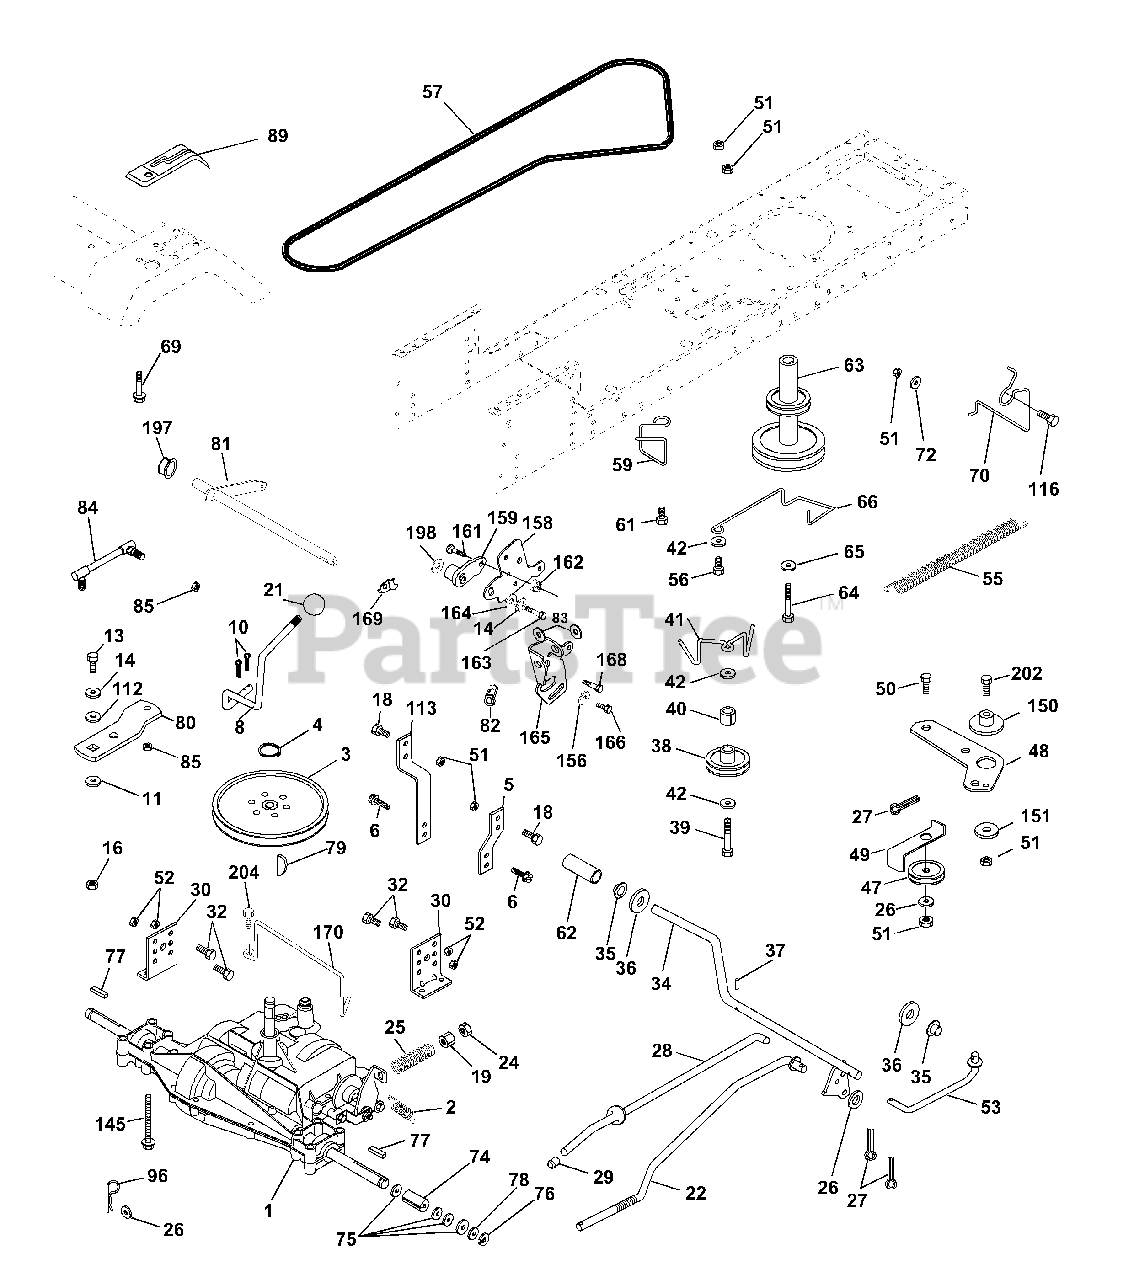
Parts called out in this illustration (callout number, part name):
2	Spring Return Brake T/a Zinc
3	Pulley Transaxle 18" tires
4	Ring Retainer # 5100-62
5	Strap Torque 30 Degrees
6	Screw 5/16-18 X 3/4
8	Rod Shift Fender Adjust Lt
10	Pin Cotter 1/8 X 1 Cad
11	Washer Plate Shf 388 Sq Hole
13	Bolt 1/4-28 Unf Gr 8 W/Patch
14	Washer Lock Hvy Helical
16	Nut Lock Hex w/ins 5/16-18
18	Bolt, Fin Hex 3/8-16 UNC x 1 Gr. 5
19	Nut Lock 3/8-16 Unc
21	Knob
22	Rod Brake Blk Zinc 26 840
24	Nut Hex Jam 3/8-16 Unc
25	Spring Rod Brake 2 00 Zinc
26	Washer 13/32 X 13/16 X 16 Ga
27	Pin Cotter 1/8 X 3/4 Cad
28	Rod Brake Parking LT/YT
29	Cap Brake Parking
30	Bracket Mtg Transaxle
32	Bolt Hex Hd 5/16-18unc X 3/4
34	Shaft Asm Pedal Foot
35	Bearing Nylon Blk 629 Id
36	Washer 21/32 X 1 X 16 Ga
37	Pin Roll 3/16 X 1"
38	Pulley Idler Flat
39	Bolt Fin Hex 3/8-16unc X 2-3/4
40	Spacer Split 395 X 59 Bzp
41	Keeper Belt Flat Idler
42	Washer 13/32 X 13/16 X 12 Ga
47	Pulley Idler V Groove Plastic
48	Bellcrank Asm
49	Retainer Belt Style Spring
50	Bolt Hex Hd 3/8-16unc X 1-1/2
51	Nut Crownlock 3/8-16 Unc
52	Nut Crownlock 5/16-18 Unc
53	Link Clutch
55	Spring Return Clutch 6 75
56	Bolt Fin Hx 3/8-16 X 1/4
57	V-Belt Ground Drive 95 25
59	Keeper Belt Span Ctr
61	Screw 3/8-16x.75
62	Cover Pedal Blk Round
63	Engine Pulley LT/YT
64	Bolt Hex
65	Washer Lock Hvy Hlcl Spr 7/16
66	Keeper Belt Engine Foolproof
69	Screw Hex wsh Hi Lo 1/4 x 1/2 unc
70	Guide Belt Mower Drive RH
72	Washer 13/32 X 1-1/4 X 12 Ga
74	Spacer Axle
75	Washer 25/32 X 1 1/4 X 16 Ga
76	E-ring #5133-75
77	Key Square 2 0 X 1845/ 1865
78	Washer 25/32 X 1-5/8 X 16 Ga
79	Key Woodruff #9 3/16 x 3/4
80	Arm Shift
81	Shaft Asm Cross Tapered PMST/20
82	Spring Torsion T/a
83	Washer 17/32 X 3/4 X 16 Ga
84	Link Transaxle PMST/20" Zinc
85	Nut Lock Center 1/4 - 28 FNTHD
89	Console Shift STLT
96	Retainer Spring 1"
112	Washer 9/32 x 3/4 x 10 Ga.
113	Strap Torque LT
116	Bolt Rdhd Sq Neck 3/8-16 x 1.25
145	Bolt Hex FLGHD 5/16-18 Gr. 5
150	Bushing Bellcrank
151	Washer 13/32 x 2 x 10
156	Washer Srrted 5/16ID x 1.125
158	Bracket Shift Mount
159	Hub Tapered Flange Shift Lt
161	Bolt Rdhd Sqnk 1/4-20 x 3/4 Gr
162	Nut Crownlock 1/4-20 Unc
163	Bolt Hex Fin 1/4-20 Unc x 1 Gr 5
164	Washer 5/8 x .281 x 10 Ga
165	Bracket Pivot Lever
166	Screw 5/16-18 x 5/8
168	Bolt Shoulder 5/16-18 x .561
169	Plate Fastening
170	Keeper Belt Transaxle Gear
197	Nyliner Snap-In
198	Washer Nyliner
202	Bolt Carr Sh 3/8-16 x 1-1/2 Gr. 5
204	Screw 5/16-18 x 1
